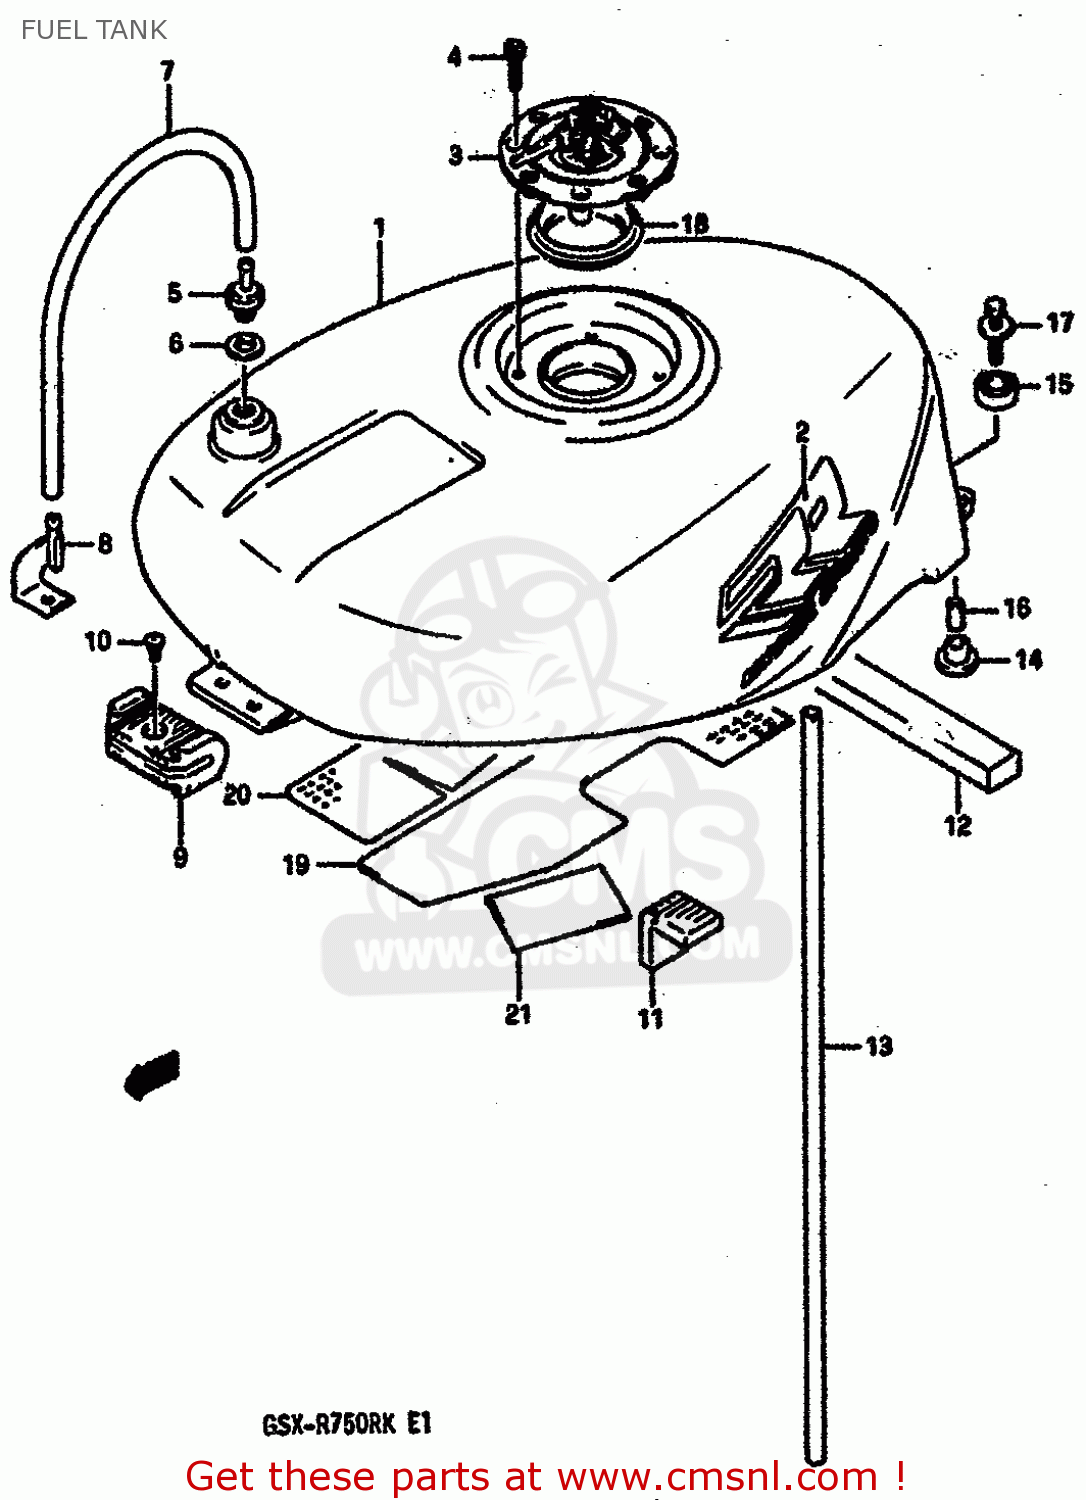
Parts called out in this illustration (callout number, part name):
1	TANK ASSY,FUEL
2	EMBLEM
3	CAP SET,FUEL TANK
4	BOLT(5X20)
5	PLUG,FUEL TANK BREATHER
6	GASKET(12.5X20X2.5) (NAS)
7	HOSE
8	HOLDER,BREATHER HOSE
9	CUSHION,FRONT
10	SCREW
11	CUSHION,SIDE
12	CUSHION, AIR SEAL
13	HOSE (7X10.2X1000)
14	CUSHION
15	CUSHION
16	SPACER (6.4X9X19)
17	BOLT(6X35)
18	SEAL,FUEL TANK INLET
19	SHIELD,FUEL TANK HEAT NO.1
20	SHIELD,FUEL TANK HEAT NO.2
21	SHIELD,FUEL TANK HEAT NO.3
